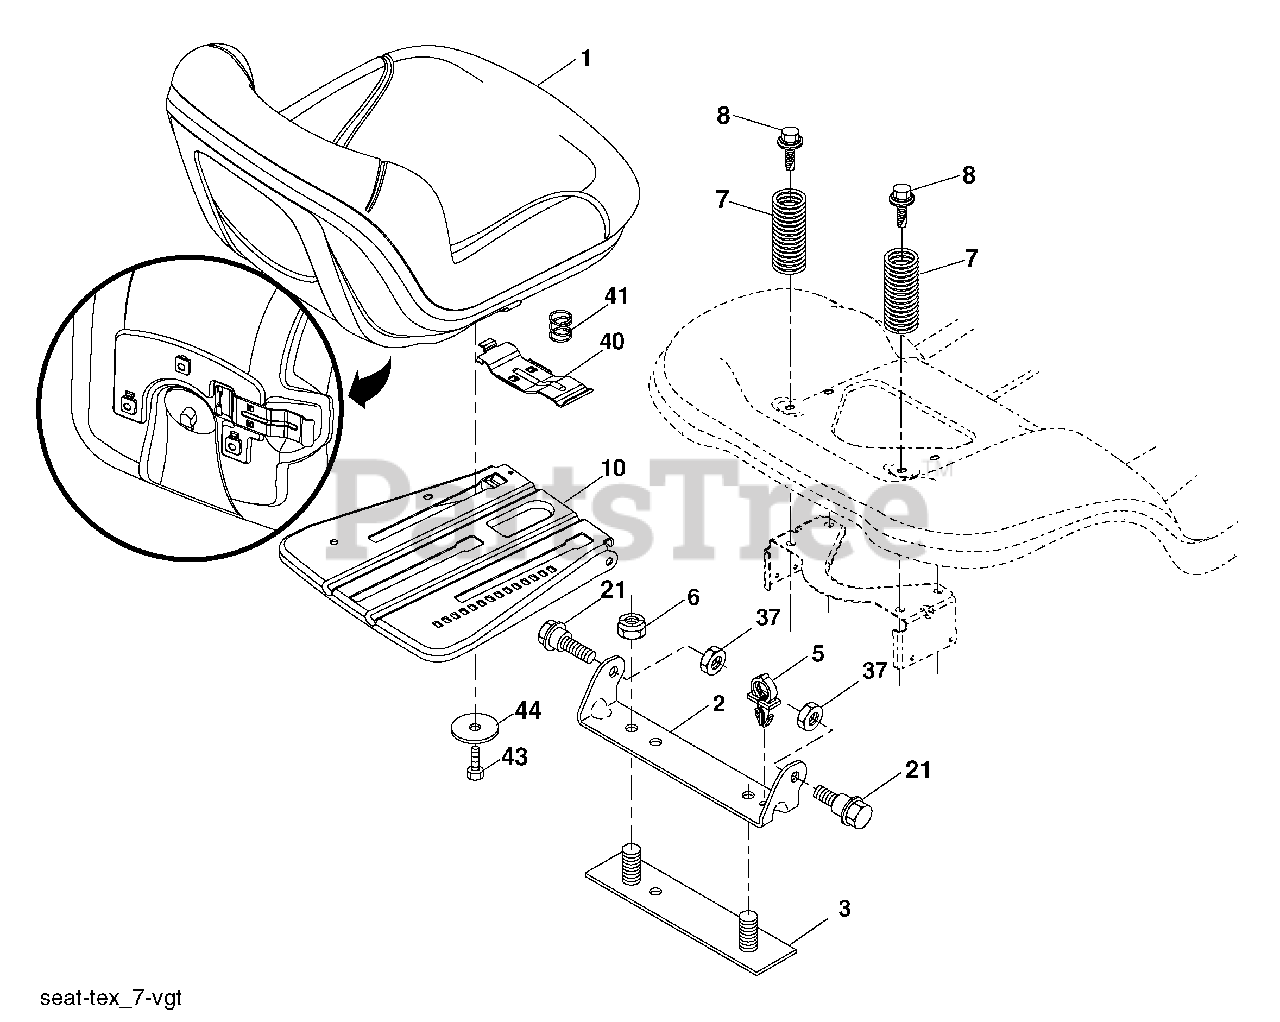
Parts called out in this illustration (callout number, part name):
1	Seat
2	Bracket Pivot Fender
3	Strap, Asm Fender
5	Clip, Push In, Hinged
6	Nut, Lock W/Ins. 3/8-16 unc
7	Spring, Seat Cprsn
8	Bolt 5/16-18 uncx 3/4 w/Sems
10	Pan, Seat
14	Bolt Rdhd Sht Nk 1/4-20 x 1-1/2
21	Bolt, Shoulder 5/16-18
37	Nut, Lock 5/16-18 unc
40	Handle Slide Seat
41	Spring Latch Seat
43	Bolt Fin Hex 3/8-16 UNC x 3/4
44	Washer 13/32 x 2-3/8 x 12Ga.
